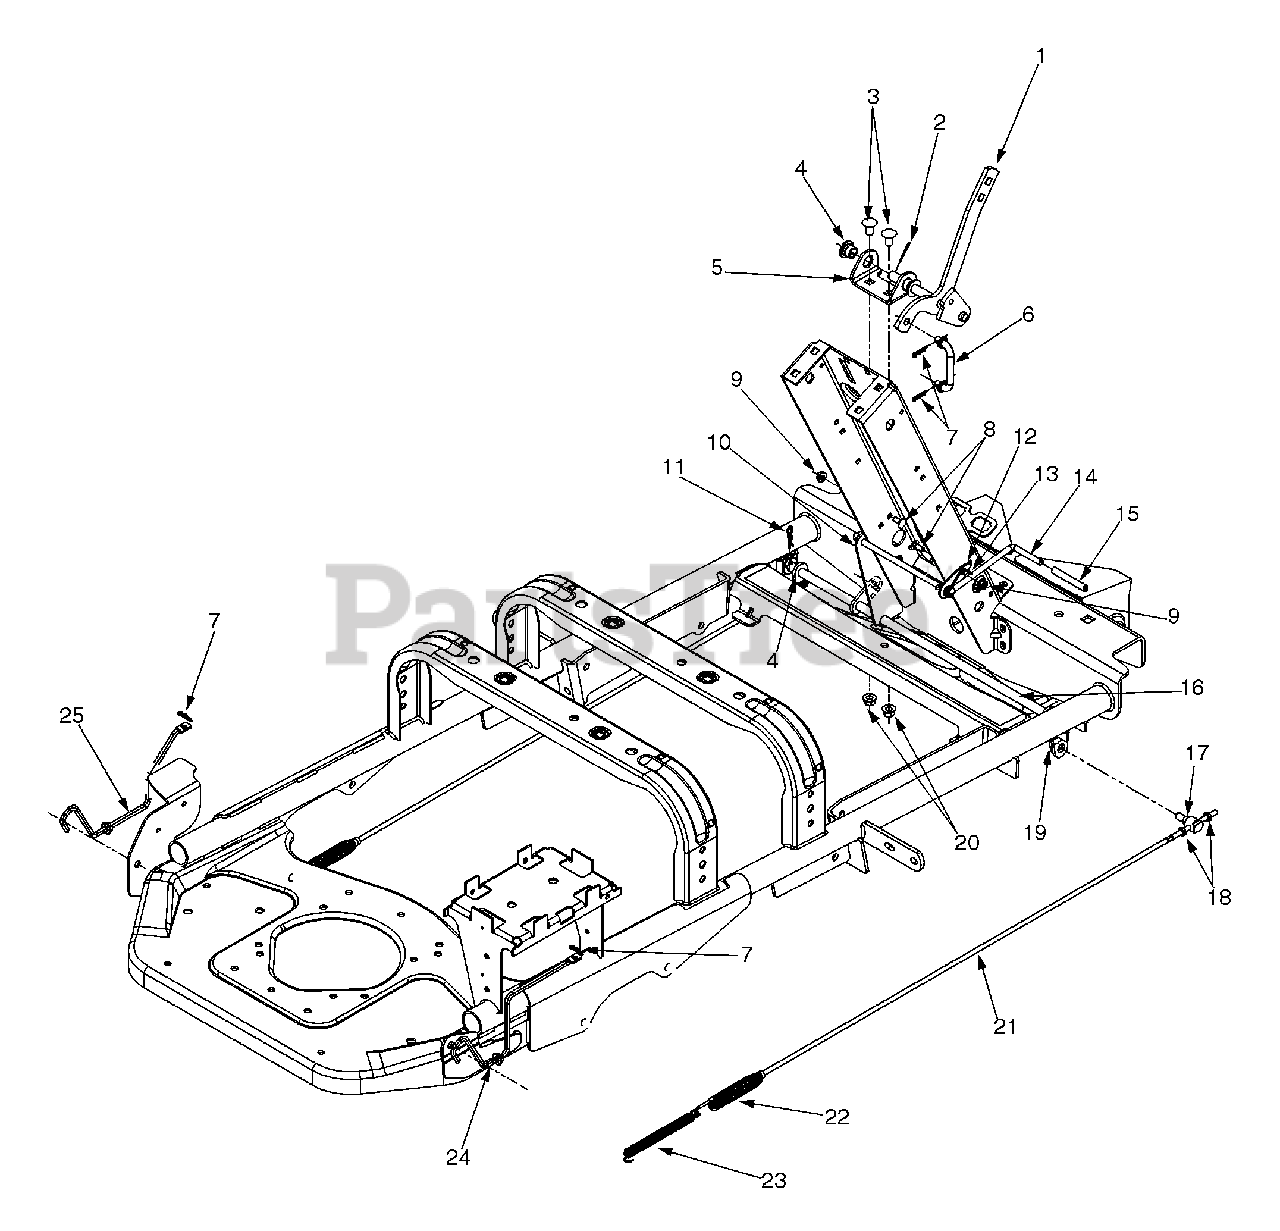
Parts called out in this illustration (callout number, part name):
1	Parking Brake Shift Ass'y
2	Cotter Pin
3	Carriage Bolt 3/8-16 x .75
4	Hex Flange Bearing .506 ID x .590
5	Brake Mounting Bracket
6	Connecting Brake Rod
7	Cotter Pin
8	Carriage Screw 1/4-20 x .62
9	Hex Flange Lock Nut 1/4-20
10	Support Plate
11	Cotter Pin
12	Retaining Rod Bracket
13	Torsion Spring 5/16
14	Parking Brake Retaining Rod
15	Parking Brake Pad
16	Brake Rod Ass'y
18	Jam Nut 1/4-28
19	Flat Washer .385 ID x 1.0 OD
20	Flange Lock Nut 3/8-16
21	Bracket Rod
22	Extension Spring
23	Extension Spring
24	Release Pump Rod RH
25	Release Pump Rod LH
